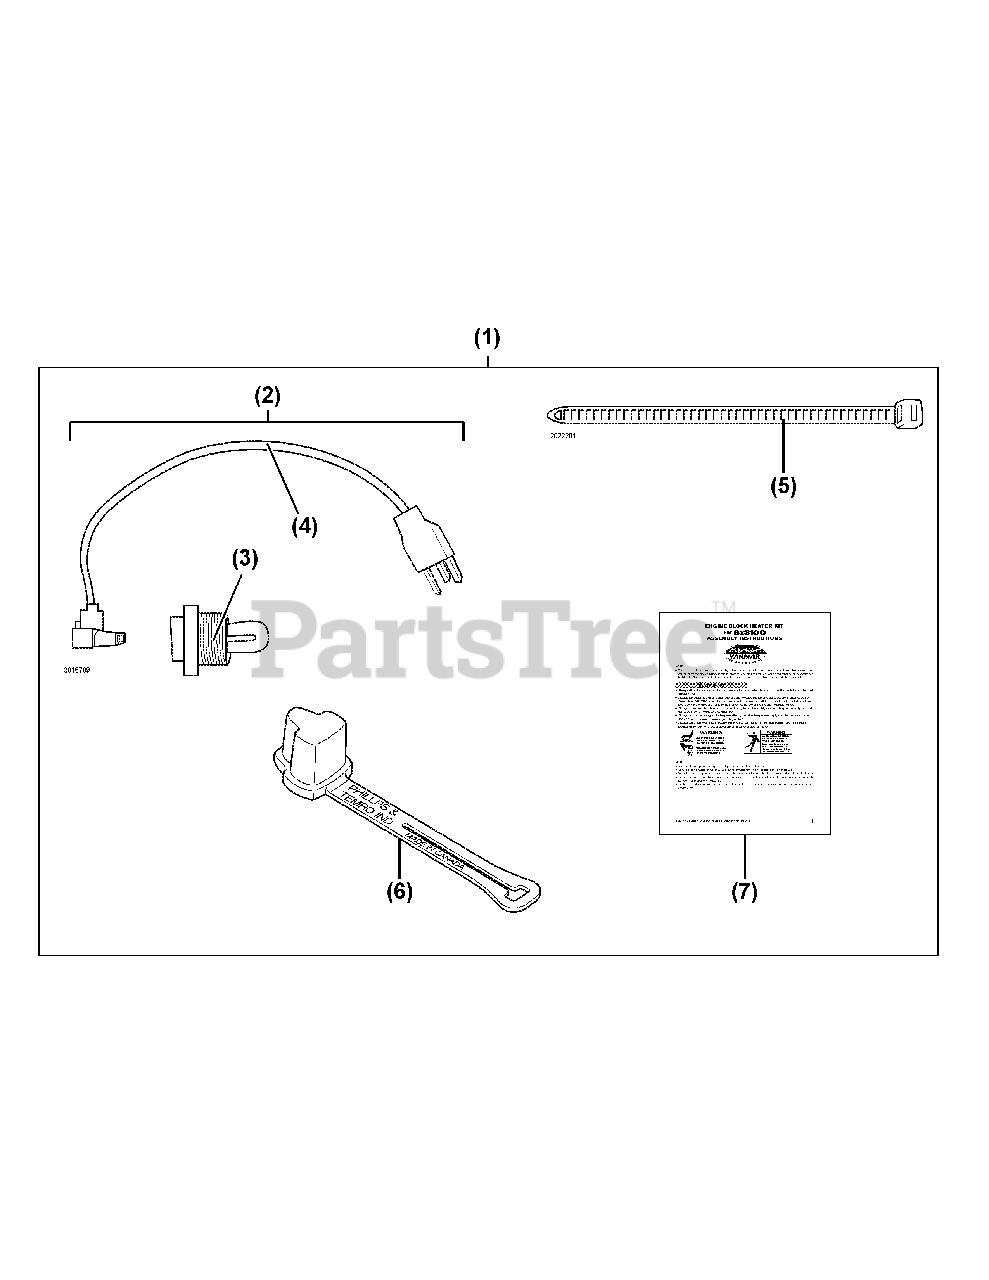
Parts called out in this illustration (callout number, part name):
1	Engine block heater kit for Sx3100
2	Optional field heater kit
3	Enigine block heater
4	Enigne block heater power cord
5	Cable tie
6	Plug protector
7	Assembly instruction
